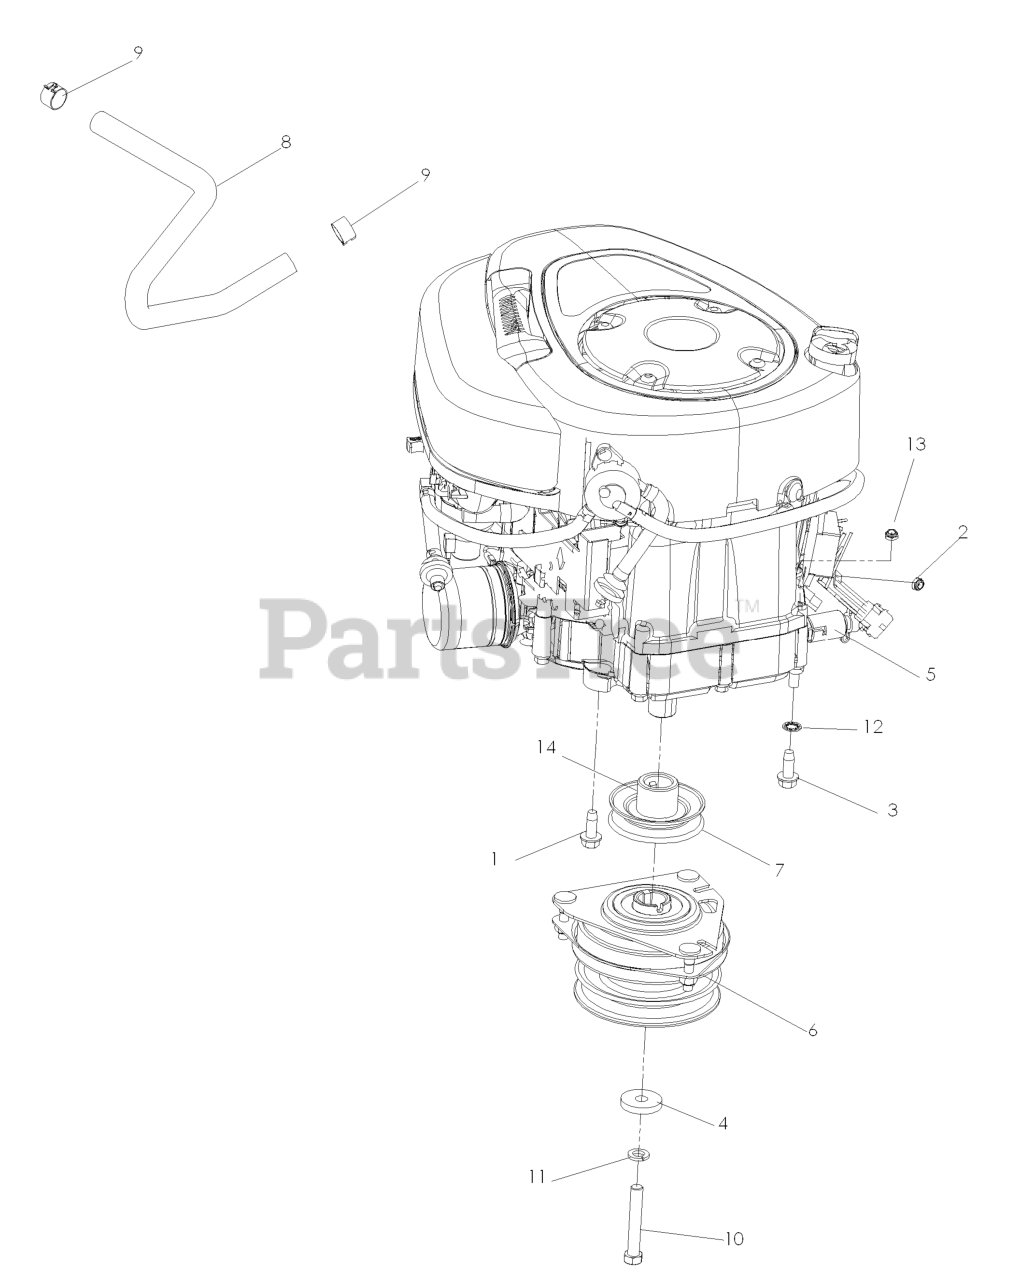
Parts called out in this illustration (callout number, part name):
1	BOLT 3/8-16 X 1.0
2	JAM NUT 1/4C (2 2 PW01)
3	BOLT 3/8-16 X 1 1/2 ZINC CLEAR
4	CLUTCH, WASHER
5	OIL DRAIN FITTING
6	CLUTCH 90 FT/LB OGURA
7	PULLEY, ENGINE
8	FUEL LINE 5"
9	HOSE CLAMP
10	HEX SCREW 7/16-20 X 3
11	WASHER 7/16 LOCK
12	WASHER, 3/8 ITLW ZN
13	NUT 3/8C CENTERBLOCK
14	SPACER, ENGINE - PULLEY
14	MUFFLER
